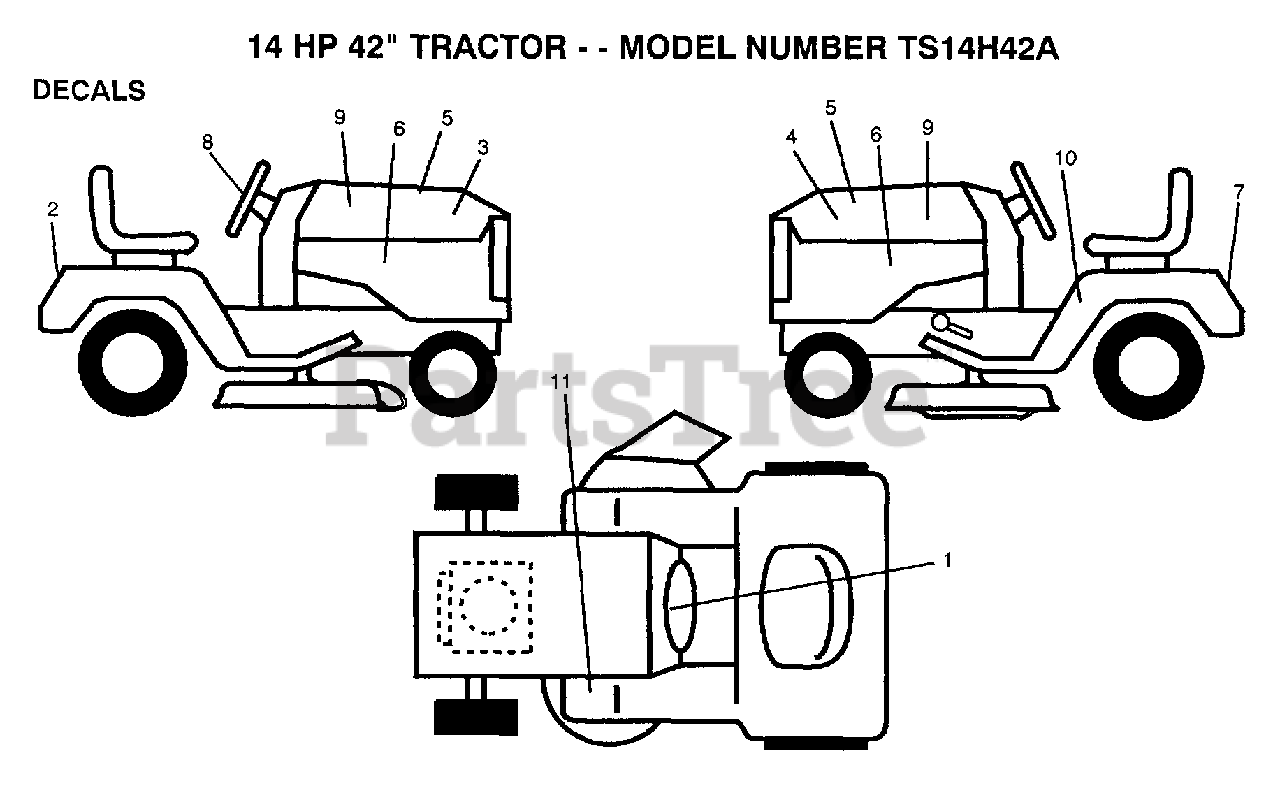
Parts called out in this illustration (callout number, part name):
2	PLATE.NAME.SMALL
3	DECAL.HOOD.RH
4	DECAL.HOOD.LH
6	DECAL.PANEL.SIDE
8	DECAL.CAP.WHEEL
10	DECAL
